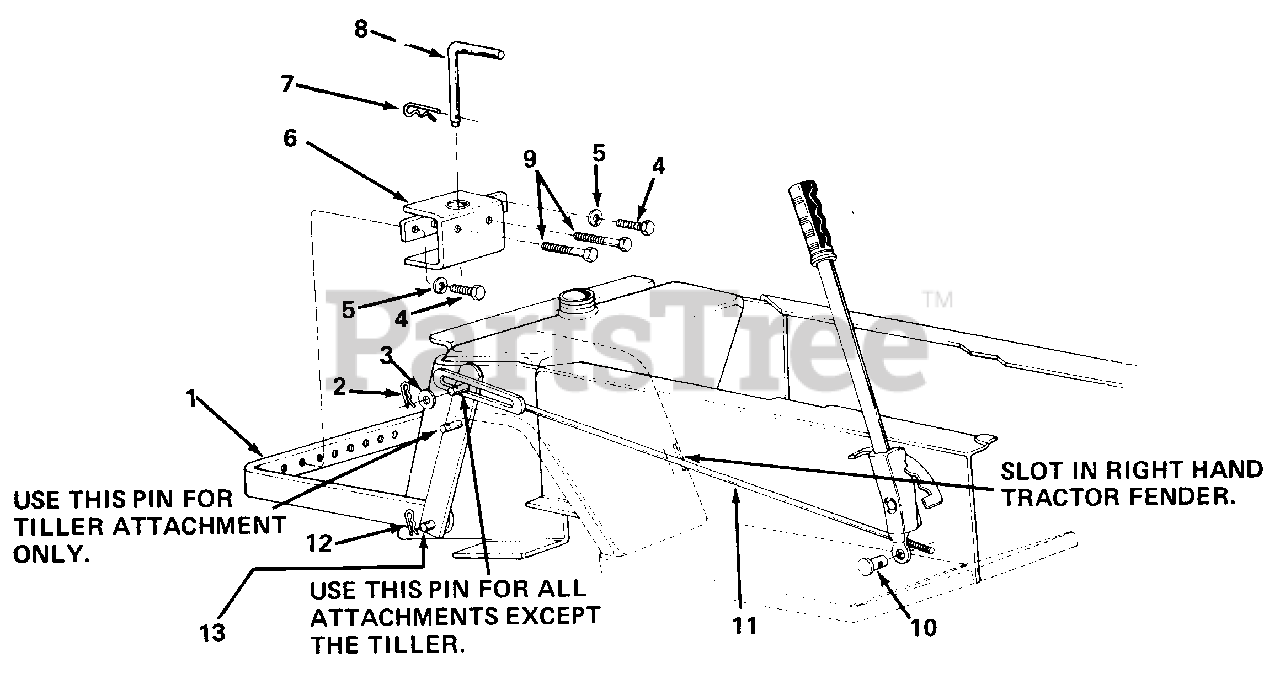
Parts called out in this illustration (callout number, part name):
3	Fl.-Wash. 1/2" I.D.
4	Hex Scr. 1/2-13 x 1.00" Lg.*
5	L.-Wash. 1/2" Scr.*
9	Hex Scr. li2-13 x 3.00" Lg. *
10	Adjustment Ferrule
